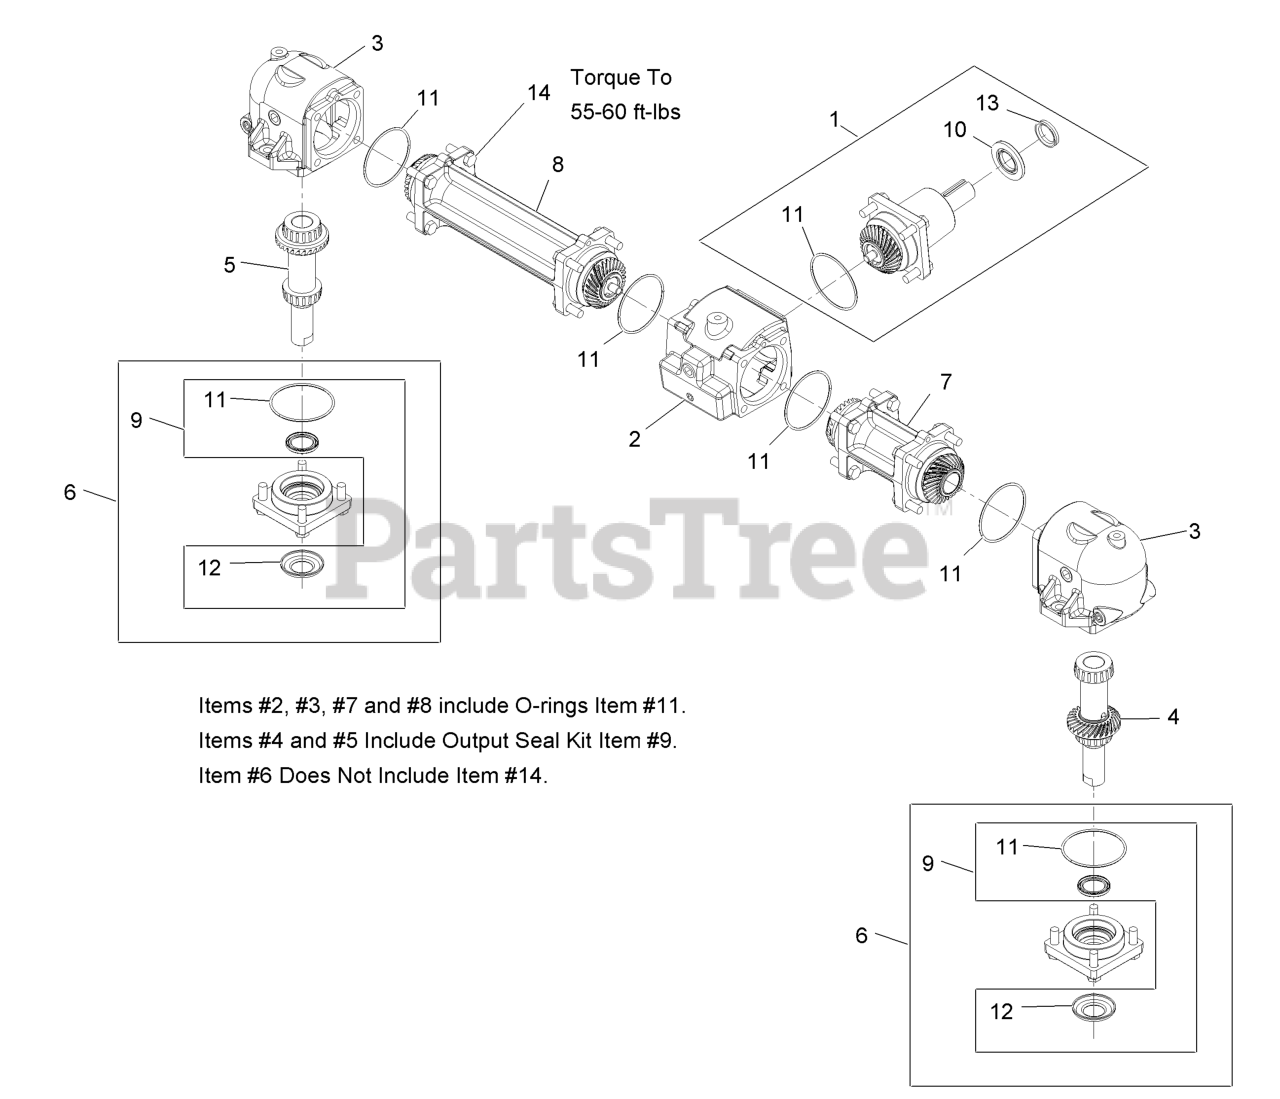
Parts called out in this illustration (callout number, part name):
1	INPUT PINION ASM
1	PINION-INPUT
2	HOUSING-CENTER
3	HOUSING-END
4	OUTPUT SHAFT AND GEAR-LH
5	OUTPUT SHAFT AND GEAR-RH
6	CAP-OUTPUT
7	TUBE-CONNECTOR, SHORT
8	CONNECTOR-TUBE, LONG
9	OUTPUT SEAL KIT
10	SEAL-INPUT
11	SEAL-O-RING
12	WASHER-CUPPED
13	SEAL-V-RING
